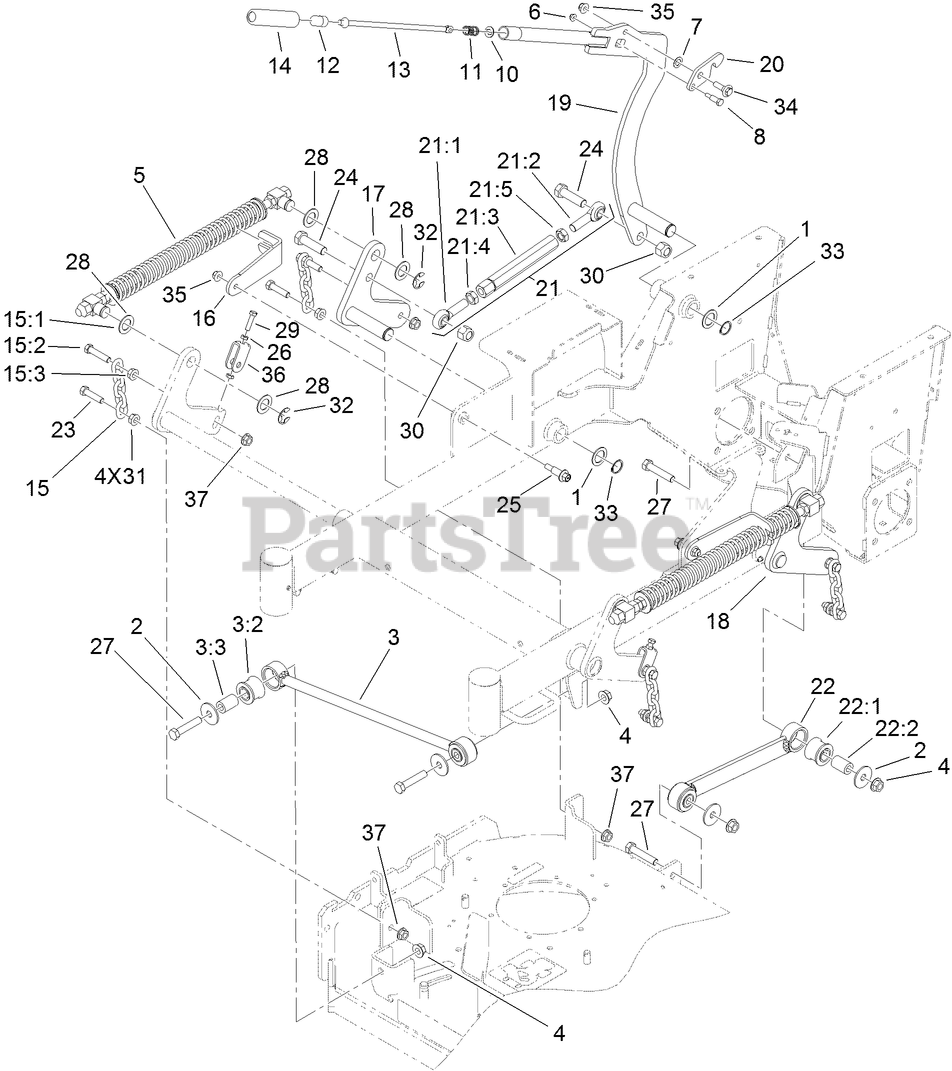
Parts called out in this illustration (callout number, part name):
1	WASHER-SPACER
2	WASHER-THRUST
3	PANHARD ROD ASM
3:2	BUSHING-SUSPENSION, RUBBER
3:3	SPACER
4	NUT-HF
5	DECK LIFT SPRING ASM
6	NUT-HF
7	WASHER
8	BOLT-SHOULDER
10	WASHER-SPECIAL
11	SPRING-COMPRESSION
13	ROD-LATCH
15	DECK LIFT CHAIN ASM
15:1	CHAIN-LIFT, DECK
15:2	SCREW-HH
15:3	NUT-HF
16	BRACKET-FORK
17	RH LIFT ARM ASM
18	LH LIFT ARM ASM
19	ARM-LIFT, HOC
20	LATCH-HOC
21	DECK LIFT LINK ASM
21:1	BALLJOINT-SPHERICAL
21:2	BALLJOINT-SPHERICAL
21:3	LINK-LIFT, DECK
21:4	NUT-JAM
21:5	NUT-JAM
22	DECK STRUT ASM
22:1	BUSHING-SUSPENSION, RUBBER
22:2	SPACER
23	SCREW-HH
24	SCREW-HH
25	BOLT-SHOULDER
26	NUT-JAM
27	SCREW-HH
28	WASHER-FLAT
29	SCREW-HH
30	NUT-LOCK, NI
31	NUT-HF
32	RING-RETAINING, EXT
33	RING-RETAINING
34	SCREW-SHOULDER, HWH
35	NUT-HF, NI
36	YOKE-ADJUST, DECK
37	NUT-HF
